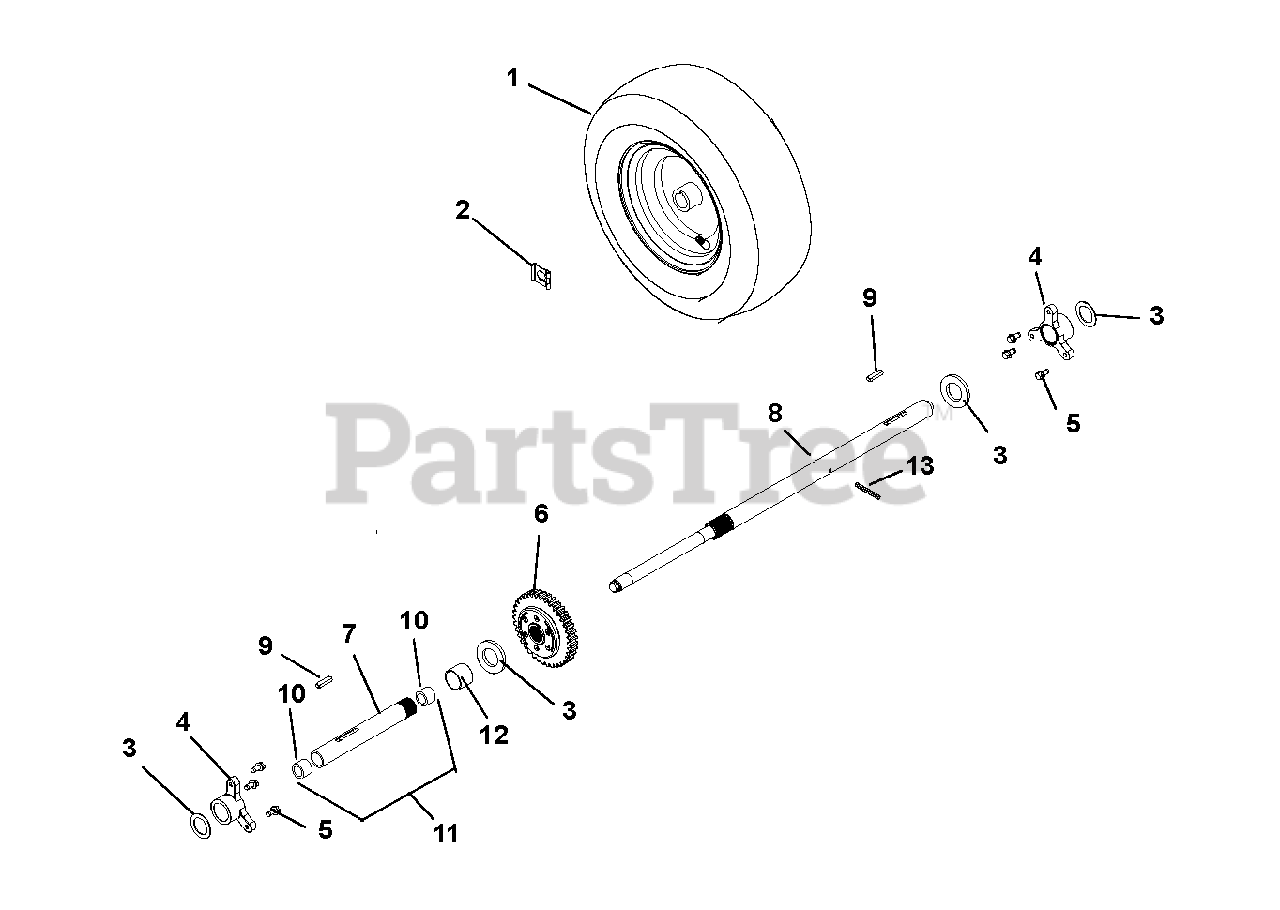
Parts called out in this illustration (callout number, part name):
1	Tire/Wheel Assembly Right Hand 15 x 5.00-6
2	Clip, Snap
3	Washer, Flat Steel 1.010 x 1.505 x .062
4	Bushing, Axle
5	Screw, Tapping Hex Washer Head Thread Rolling .25-20 x .50
6	Differential Assembly
7	Axle, Short (Included in Item 11)
8	Axle, Long
9	Key Rectangular .25 x .188 x 1.00
10	Bushing, Sleeve (Included in Item 11)
11	Axle, Short with Bushings (Includes Items 7 and 10)
12	Bushing, Sleeve
13	Pin, Roll .188 x 1.25
